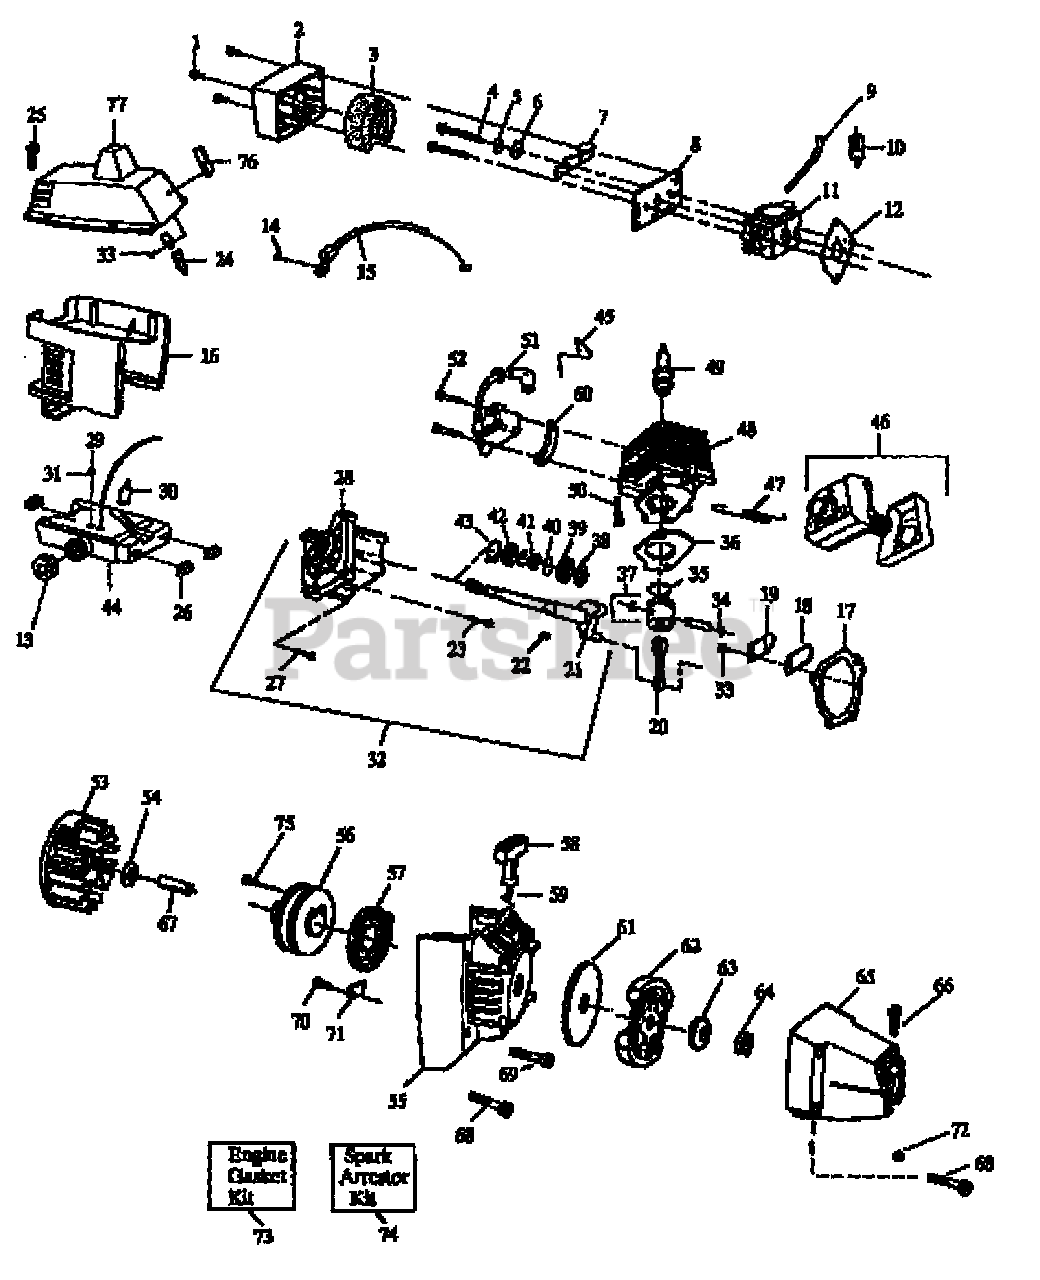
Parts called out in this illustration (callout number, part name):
2	Air Filter Cover
3	Air Filter
5	Spacer
6	Wave Washer
7	Choke Shutter
8	Air Filter Plate
9	Fuel Line Kit
10	Fuel Pick-up Ass'y.
11	Carburetor
12	Carburetor Gasket
13	Fuel Cap Ass'y.
15	Throttle Cable Ass'y.
16	Shroud
17	Crankcase/Shroud Gasket
20	Connecting Rod Ass'y.
21	Crankshaft Ass'y.
22	Flywheel Key
24	Switch Retainer
28	Crankcase Ass'y.
29	Check Valve
30	Filter Element
32	Crankcase & Crankshaft Ass'y
33	Screw
34	Piston Pin Retainer
35	Piston Ring
36	Cylinder Gasket
37	Piston Kit
39	Inner Bearing
40	Retaining Ring
41	Crankshaft Seal
42	Outer Bearing
43	Crankshaft Retaining Ring
44	Fuel Tank Ass'y.
45	Switch Wire Form
46	Muffler Kit
47	Muffler Attachment Spring
48	Cylinder
49	Spark Plug
51	Ignition Module Kit
52	Screw
53	Flywheel Ass'y.
54	Washer
55	Fan Housing
56	Starter Pulley Kit
57	Starter Spring
58	Starter Handle
59	Rope Kit
60	Spacer (Model GT26 Only)
61	Clutch Washer
62	Clutch Ass'y. Kit
65	Clutch Housing
73	Engine Gasket Kit
74	Spark Arrestor Kit
75	Screw
76	Switch Lever
77	Cylinder Cover
